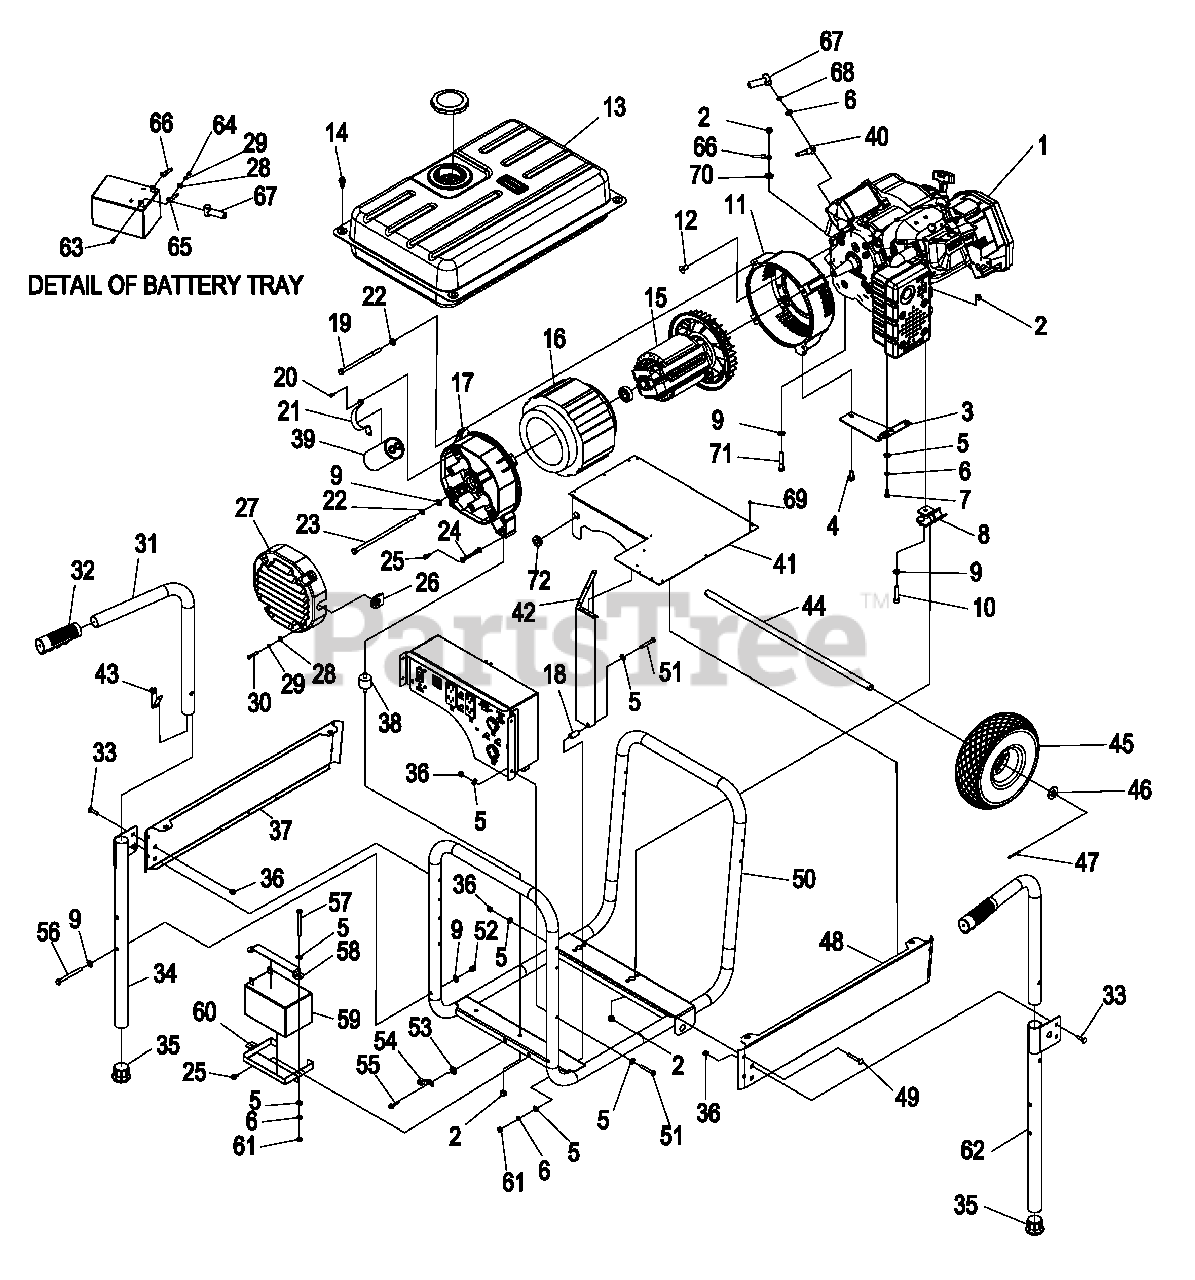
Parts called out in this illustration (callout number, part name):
1	ASSEMBLY, ENGINE GH-410 PORTABLE
2	NUT HEX LOCK M8-1.25 NY INS
3	BRACKET MUFFLER
4	SCREW HHTR 5/16-18 X 3/4
5	WASHER FLAT 1/4-M6 ZINC
6	WASHER LOCK M6-1/4
7	SCREW HHC M6-1.0 X 16 G8.8
8	VIBRATION MOUNT
9	WASHER FLAT 5/16-M8 ZINC
10	SCREW SHC M8-1.25 X 40
11	ENGINE ADAPTER HOUSING
12	SCREW FHSC 3/8-16 X 3/4
13	FUEL TANK ASSY 8KW PORTABLE
14	SCREW HHTT M8-1.25 X 20
15	ROTOR 8KW
16	STATOR 8KW
17	BEARING CARRIER REAR
18	SPACER 1/2 X 1/4 X 1
19	SCREW HHC M8-1.25 X 140 G8.8
20	SCREW PPHM M4-0.7 X 10
22	WASHER LOCK M8-5/16
23	SCREW IHHC 5/16-24 X 8-1/2 G5
24	GROUND WIRE BEARING CARRIERFRAME
25	SCREW HHTT M6-1.0 X 12
26	GROMMET WIRE SLEEVE
27	COVER ALTERNATOR INLET
28	WASHER FLAT #10 ZINC
29	WASHER LOCK #10
30	SCREW PPHM M5-0.8 X 30
31	HANDLE PORTABLE
32	FINGERED GRIP
33	BOLT CARRIAGE 1/4-20 X 1
34	HANDLE LEG PORTABLE LEFT SIDE
35	1-3/8" RUBBER END GENERATOR FOOT
36	NUT HEX LOCK 1/4-20 NYL INS
37	RAIL TANK SUPPORT ALT. SIDE
38	MOUNTS VIBRATION
39	CAPACITOR MOTOR RUN 47MF 440V
40	WIRE, #16 START SOL-STARTER
41	DEFLECTOR TANK HEAT
42	DEFLECTOR, HEAT
43	SNAP BUTTON - .437" DIA. HEAD
44	AXLE 5/8" DIAMETER
45	WHEEL, SOLID RUBBER 10" O.D.
46	WASHER FLAT 5/8 ZINC
47	PIN COTTER 1/8 X 1-1/4 ZINC PLATED
48	RAIL TANK SUPPORT MUFFLER SIDE
49	BOLT CARRIAGE 1/4-20 X 1-3/4
50	CRADLE PORTABLE
51	SCREW HHC 1/4-20 X 1.75 G5
52	NUT HEX LOCK 5/16-18 NYL INS
53	WASHER LOCK SPECIAL 1/4"
54	LUG SLDLSS #2-#8 X 17/64 CU
55	SCREW HHTT M6-1.0 X 25
56	SCREW HHC 5/16-18 X 3-1/4 G5
57	SCREW HHC 1/4-20 X 3 G5
58	BRACKET BATTERY HOLD DOWN
59	BATTERY 12V 10Ah
60	BRACKET BATTERY TRAY
61	NUT HEX 1/4-20 STEEL
62	HANDLE LEG PORTABLE RIGHT SIDE
63	SCREW HHC M5-0.8 X 12 G8.8
64	NUT HEX M5-0.8 G8 CLEAR ZINC
65	WIRE, STARTER SOL-BATTERY
66	WIRE, BATTERY (-) TO ENGINE FRAME
67	BOOT, BATTERY CABLE
68	NUT HEX M6 X 1.0 G8 YELLOW CHROME
69	RIVET POP .125 X 0.337 STEEL
70	WASHER LOCK SPECIAL 5/16
71	SCREW HHC M8-1.25 X 50 C8.8
72	GROMMET
